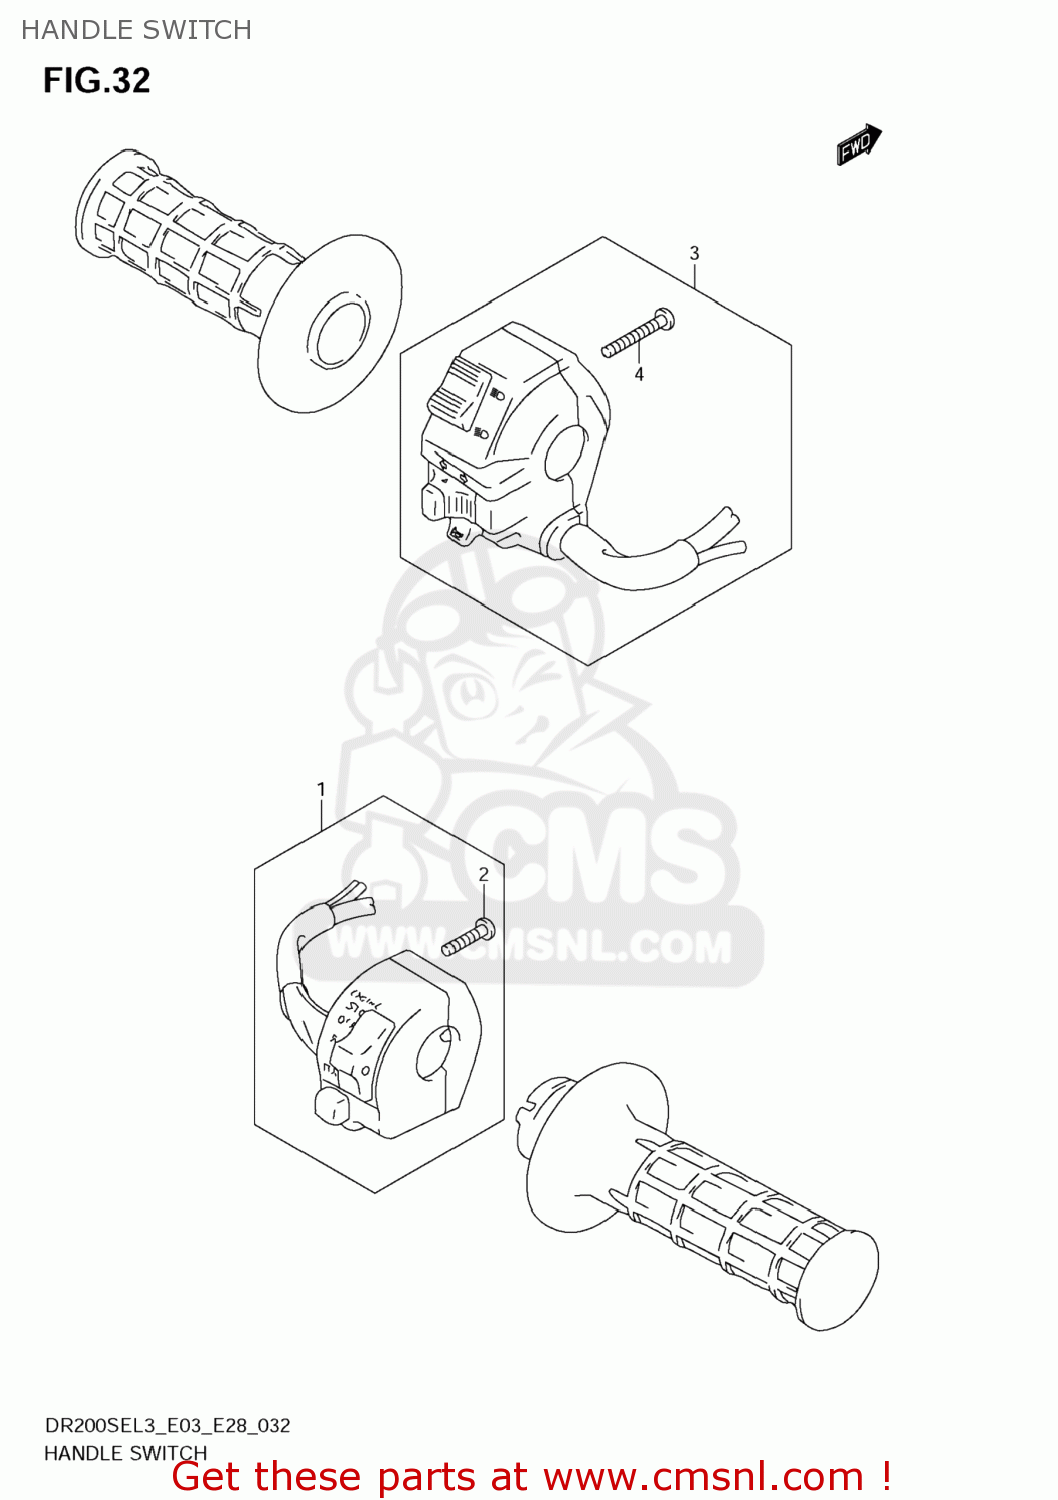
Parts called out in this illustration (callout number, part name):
1	SWITCH ASSY,HANDLE,R
2	SCREW
3	SWITCH ASSY,HANDLE,L
4	SCREW
